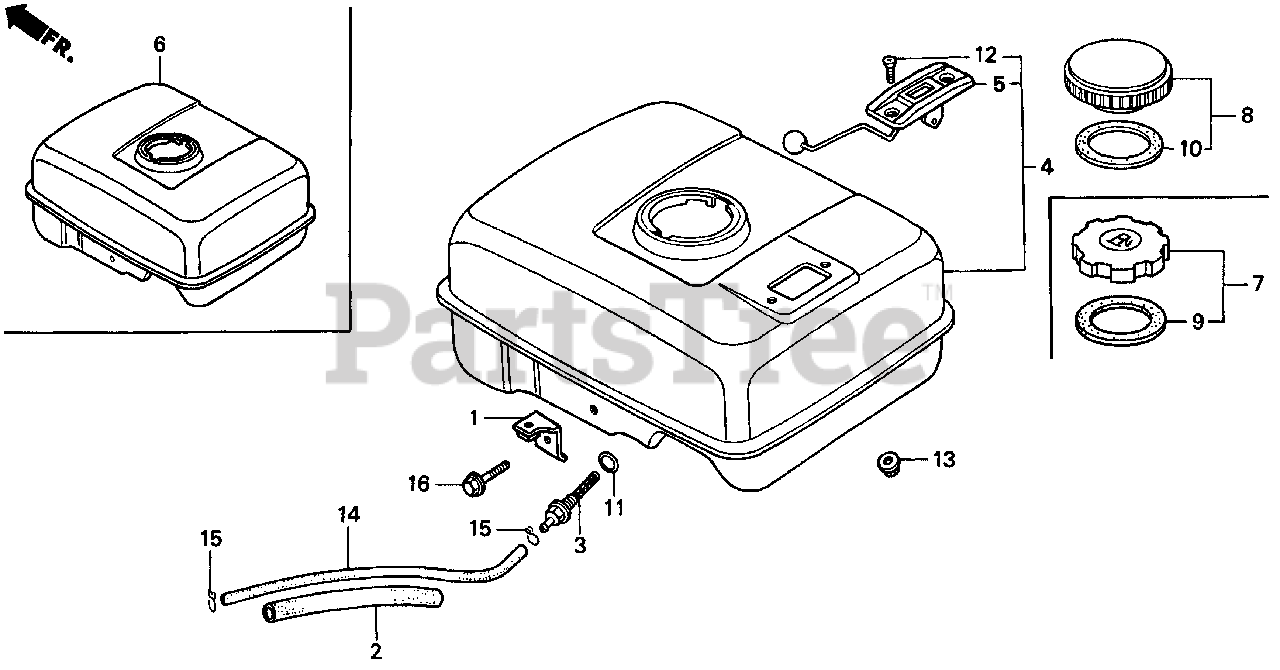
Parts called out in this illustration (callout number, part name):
1	STAY, ENGINE CONTROL COVER
2	RUBBER, SUPPORTER (107MM)
3	JOINT, FUEL TANK
4	TANK ASSY., FUEL *R280* (GAUGE) (POWER RED)
5	GAUGE ASSY., FUEL
7	CAP, FUEL FILLER
9	GASKET, FUEL FILLER CAP
11	O-RING (13.5X1.5) (ARAI)
12	SCREW, FLAT (5X10)
13	NUT, FLANGE (6MM)
14	BULK HOSE, FUEL (4.5X3000) (4.5X140)
15	CLIP, TUBE (B8)
16	BOLT, FLANGE (6X25)
